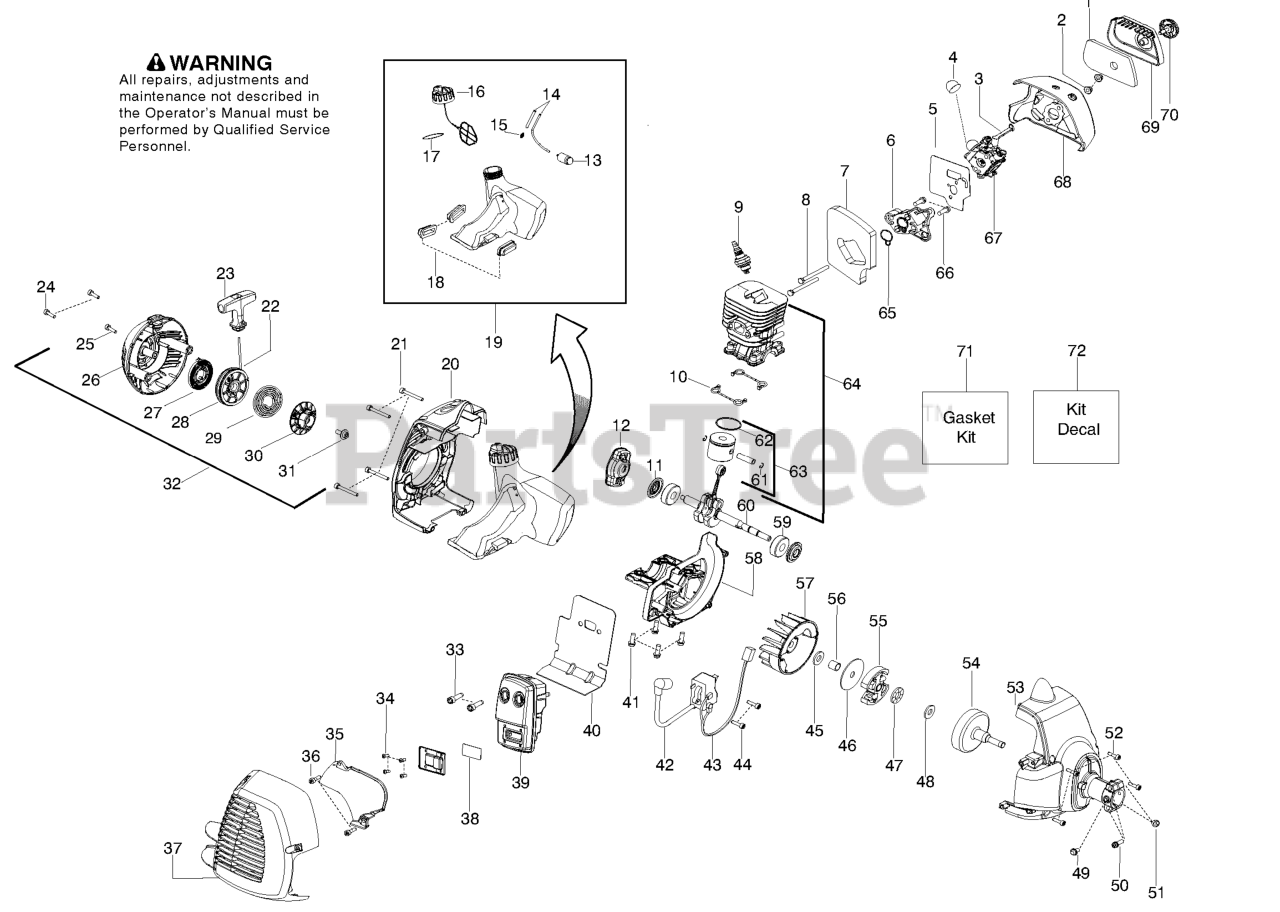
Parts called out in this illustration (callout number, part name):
1	FILTER AIRBOX
3	CHOKE LEVER
4	PURGE BULB ZAMA
5	KIT GASKET CARB 28CC
6	CARB ADAPTOR
7	KIT GASKET 28CC
8	BOLT CARB ADAPTOR
9	Plug-Spark (RCJ-8Y)
10	KIT GASKET 28CC
11	KIT GASKET 28CC
12	STARTER PAWL BRIDGE
13	FUEL PICK-UP ASSY
14	KIT-LINE(FUEL)
15	FUEL LINE FITTING
16	ASSY-CAP W/RETAINER
17	KIT GASKET 28CC
18	ISOLATOR FUEL TANK
19	KIT FUEL TANK HVA
20	KIT STARTER HSG HVA 128
22	KIT ROPE
23	HANDLE - STARTER
24	SCREW M5-0.8X30MM
25	SCREW M4 X 1.75 PT 16MM
26	KIT STARTER HSG HVA 128
27	KIT STARTER SPRING
28	KIT STARTER PULLEY
29	SPRING - DRIVER
30	DRIVER PULLEY
32	ASSY STARTER HSG HVA
33	BOLT MUFFLER
34	SCREW-6-19X5/16PLAST PA
35	SHIELD HEAT
36	SCREW M4 X 1.75 PT 16MM
37	KIT MUFFLER GUARD HVA
38	KIT SPARK ARRESTOR SCREEN
39	KIT MUFFLER LE28
40	KIT GASKET 28CC
41	SCREW-M5-0.8 X 25MM(TAP)
42	IGNITION MODULE MBU-7
43	ASSY MODULE LEAD WIRE
44	SCREW M4 X .70 TT 16MM
45	WASHER CLUTCH
46	WASHER-CLUTCH
47	BEARING THRUST
48	WASHER THRUST
49	Screw
50	Screw
51	LOCKNUT-HEX 10-24
52	SCREW M4 X .70 TT 16MM
53	Assy-Fan Housing
54	ASSY-CLUTCH DRUM
55	ASSEMBLY CLUTCH
56	SPACER FLYWHEEL
58	CRANKCASE CAST LE28
59	BEARING RADIAL BALL (6201)
60	ASSY CRANKSHAFT
61	WRIST PIN RET.
62	RING PISTON
63	KIT - PISTON
64	KIT PISTON CYL
65	KIT GASKET 28CC
66	SCREW-M5-0.8 X 25MM(TAP)
67	KIT CARB
68	RP_AIR BOX
69	COVER-AIR BOX
70	KNOB ASSY AIRBOX COVER
71	KIT GASKET 28CC
